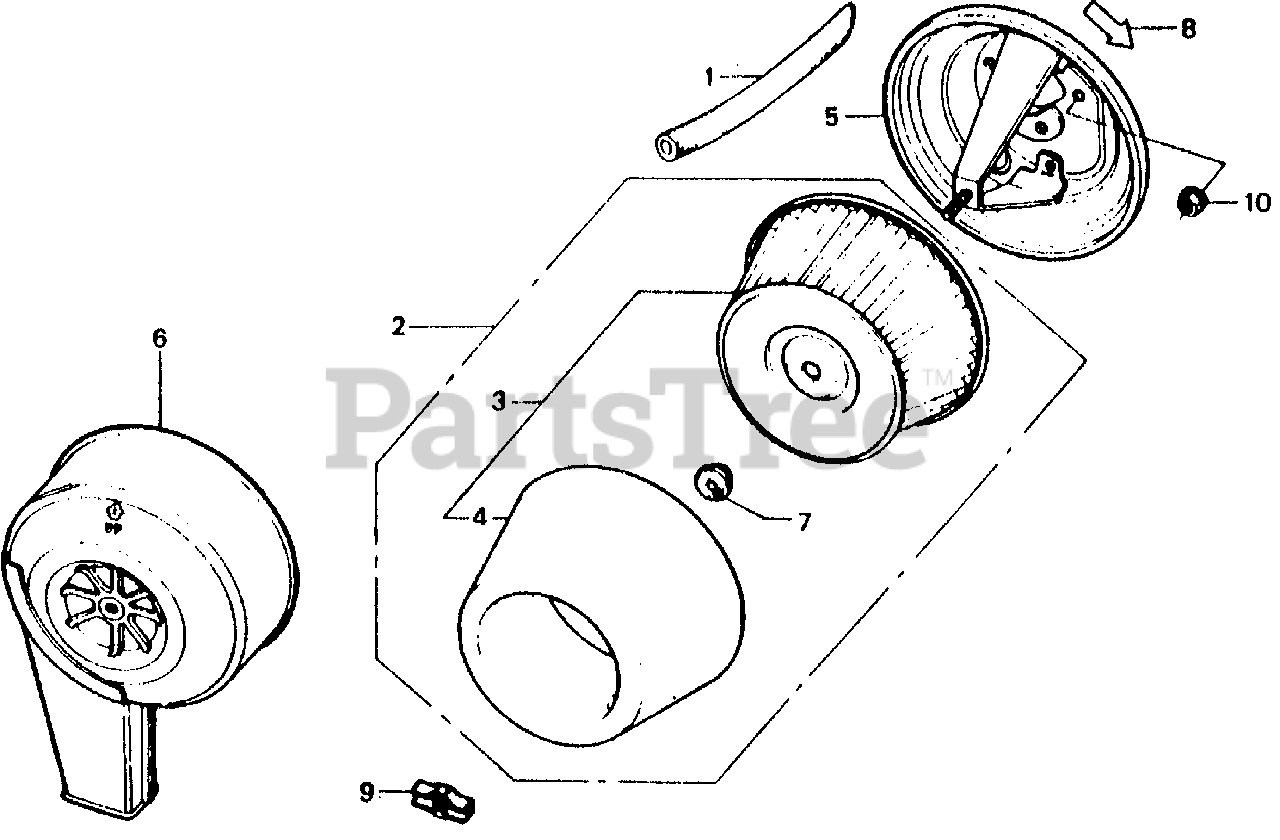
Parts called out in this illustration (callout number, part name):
1	TUBE, BREATHER
2	ELEMENT, AIR CLEANER
3	ELEMENT, AIR CLEANER
4	FILTER (OUTER)
5	HOUSING, AIR CLEANER
6	COVER, AIR CLEANER
7	GROMMET, AIR CLEANER
8	MARK, CHOKE
9	WINGNUT, AIR CLEANER COVER
10	NUT, FLANGE (6MM)
